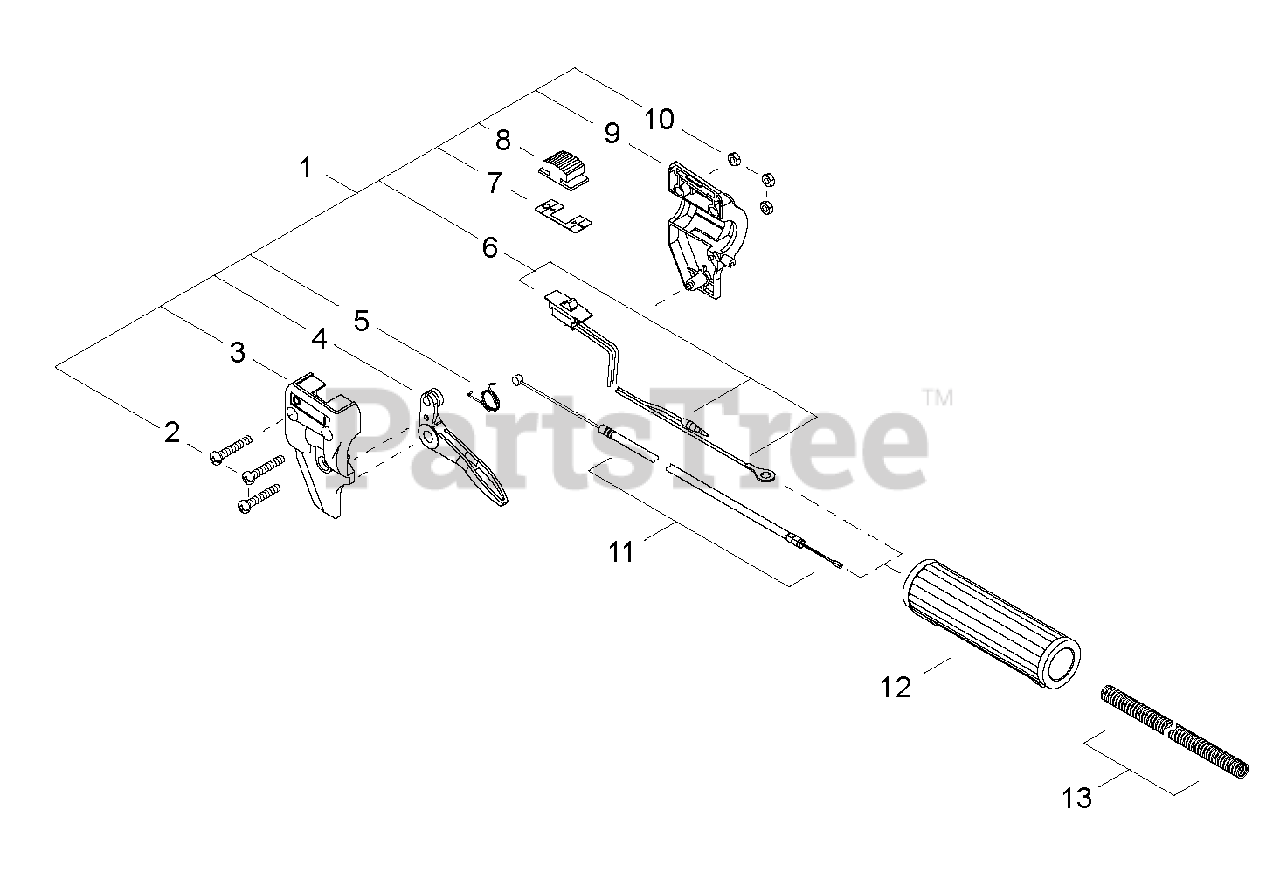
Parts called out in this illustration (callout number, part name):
1	THROTTLE CONTROL ASSY
2	SCREW M5×30
3	CONTROL HANDLE - LEFT
4	TRIGGER, THROTTLE
5	SPRING, RETURN
6	SWITCH, ON-OFF
7	PLATE, SWITCH
8	KNOB, SWITCH
9	CONTROL HANDLE - RIGHT
10	NUT M5
11	CABLE, THROTTLE
12	GRIP
13	TUBE, PLASTIC PROTECTIVE
